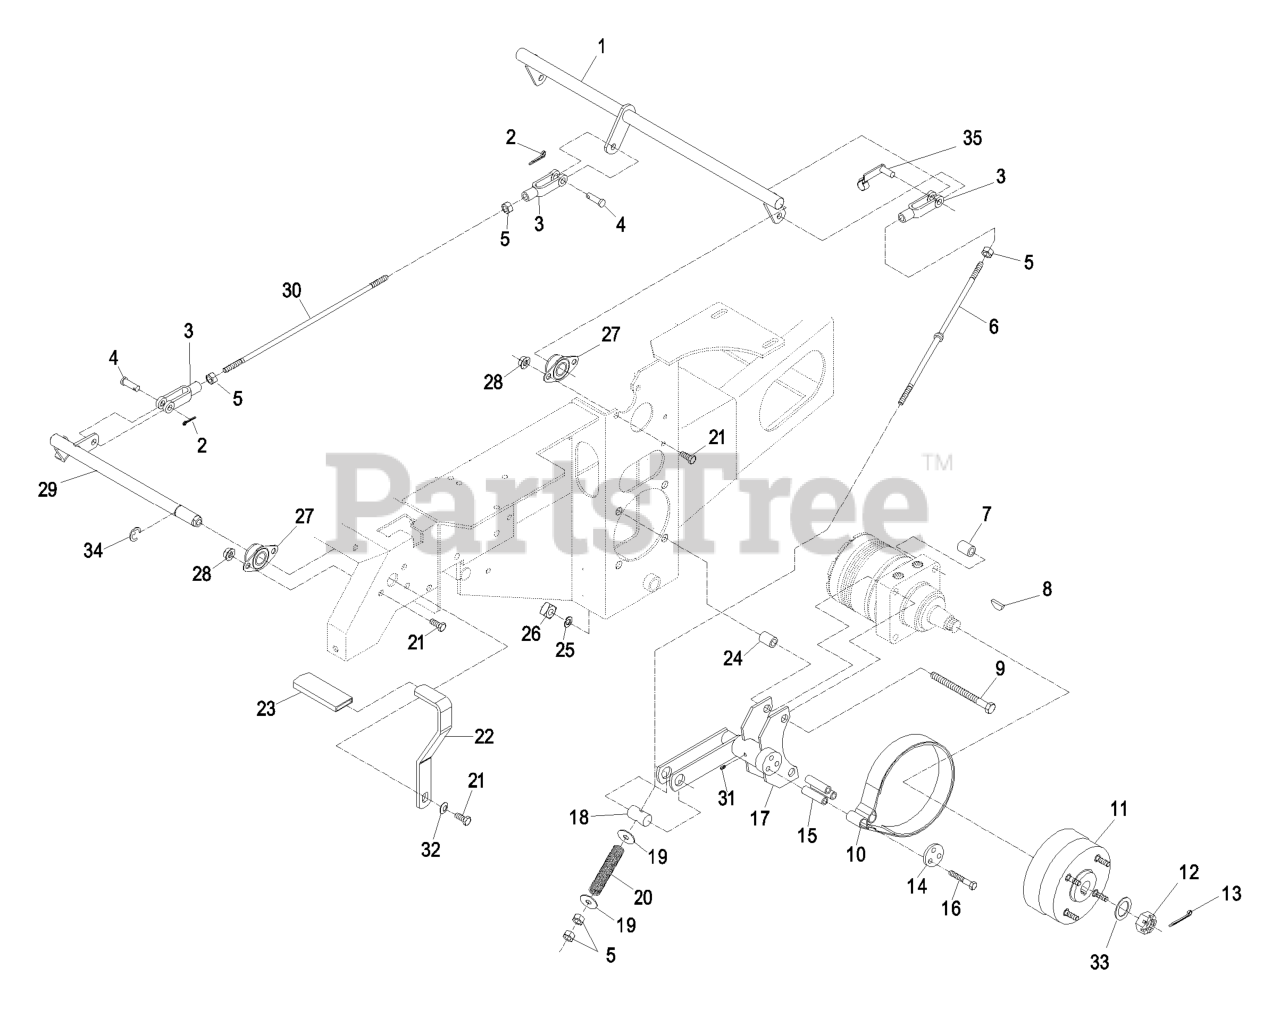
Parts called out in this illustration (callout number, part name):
1	CRANK-BRAKE, PARK
2	PIN-COTTER
3	YOKE-LINKAGE, BRAKE
4	PIN-CLEVIS
5	NUT-HEX
6	ROD-BRAKE
7	SPACER-WHEEL
8	KEY-WOODRUFF
9	SCREW-HH
11	WHEEL HUB ASM
13	PIN-COTTER
14	RETAINER-BAND, BRAKE
16	SCREW-HH
17	BRACKET-BRAKE
18	PIN-TRUNION
19	WASHER-FLAT
20	SPRING-BRAKE
21	SCREW-HH
22	ASM,BRAKE HANDLE W/ GRIP
23	GRIP-LEVER
24	SPACER-WHEEL
25	WASHER-LOCK
27	BEARING-FLANGE, SIDE
28	NUT-HHF, WHIZ
29	SHAFT-BRAKE, PARKING
30	LINKAGE-HANDLE, BRAKE
31	FITTING-GREASE
32	WASHER-BELLEVILLE
33	WASHER-SPACER
35	PIN-SPRING, CLEVIS
